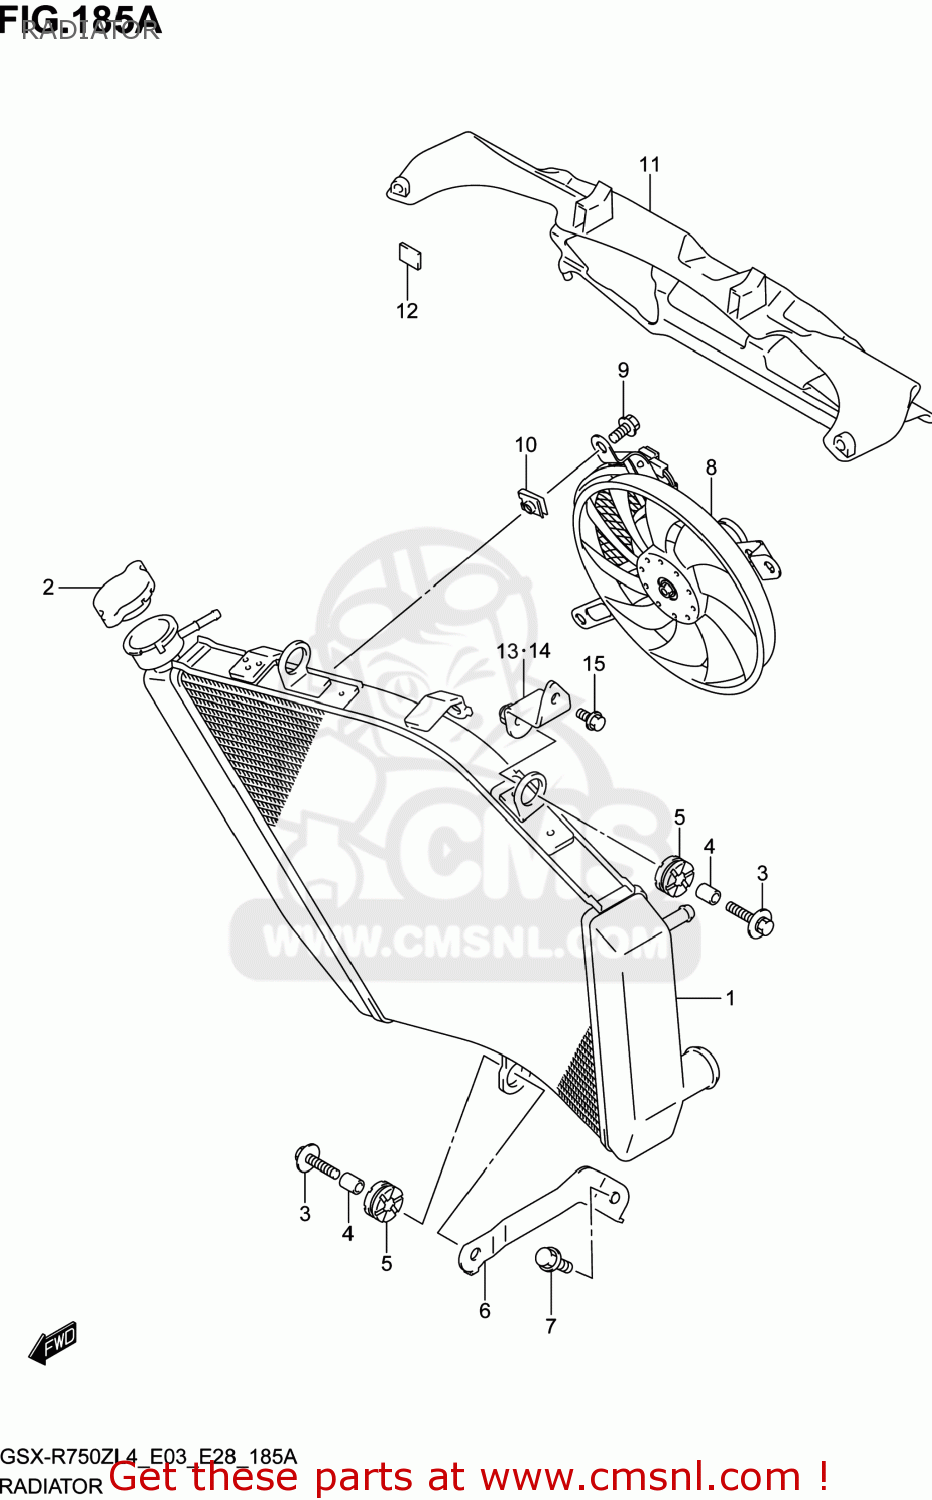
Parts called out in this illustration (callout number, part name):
1	RADIATOR ASSY,WATER
2	CAP,RADIATOR(1.1)
3	BOLT(6X25)
4	SPACER(6.5X10X12)
5	CUSHION
6	BRACKET,RADIATOR
7	BOLT
8	FAN ASSY,RADIATOR
9	BOLT,FAN ASSY
10	NUT,RADIATOR FAN
11	SHIELD,RADIATOR HEAT
12	PAD
13	BRACKET,RADIATOR UPR,R
14	BRACKET,RADIATOR UPR,L
15	BOLT
